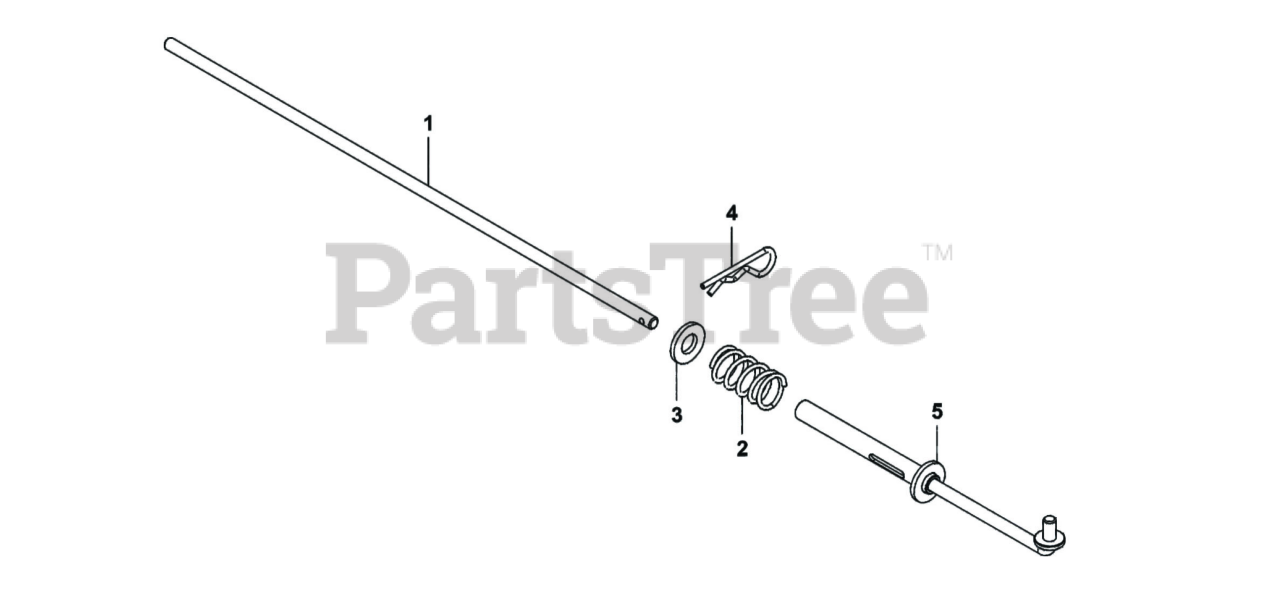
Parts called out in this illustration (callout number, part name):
1	LATCH ROD-HOOK SIDE
3	1/2" Flat Washer 1.084 Odx.528IDx.120T
4	HAIR PIN CLIP
5	LATCH ROD WELDMENT
